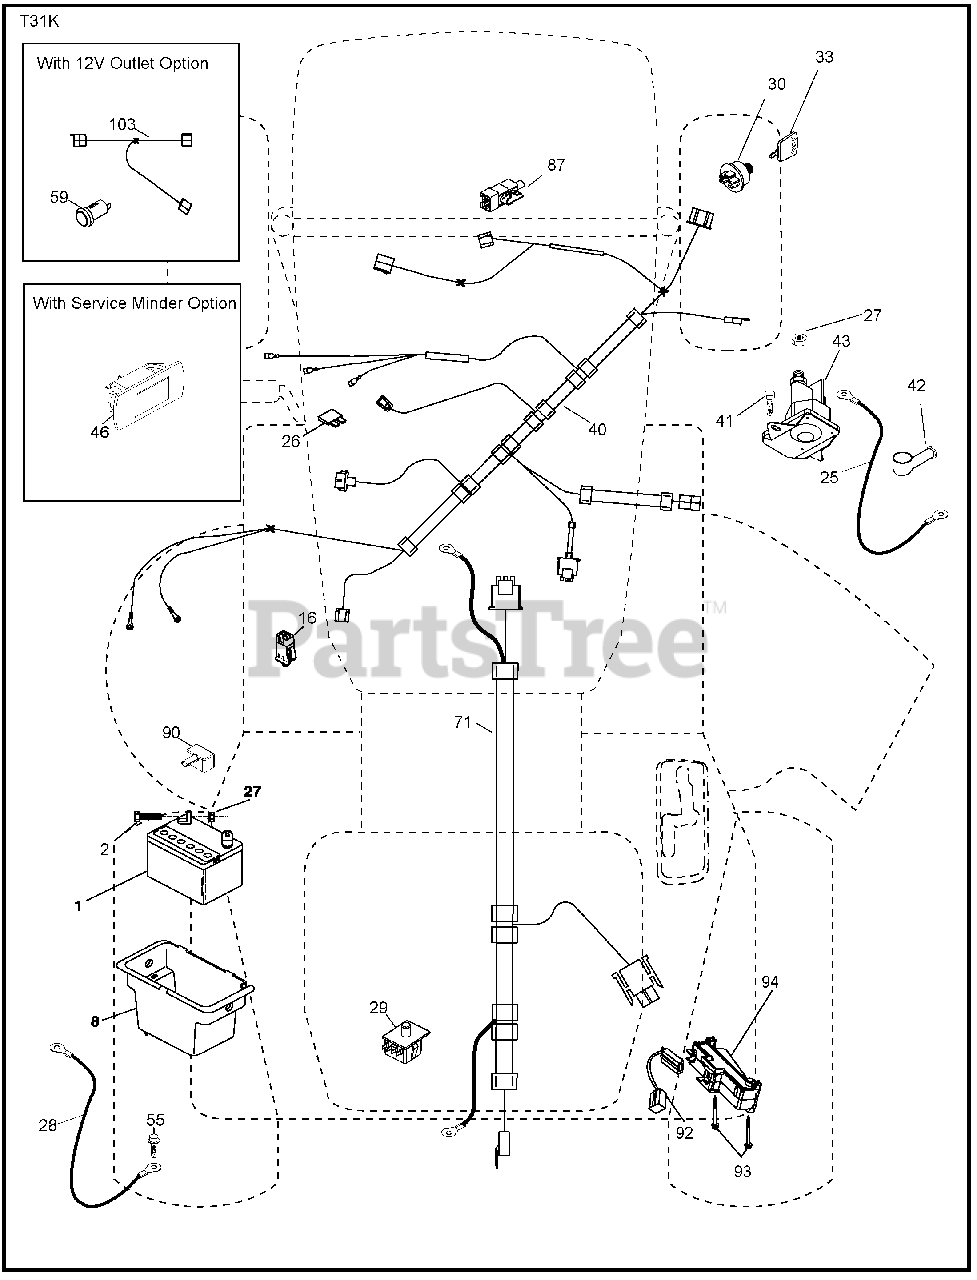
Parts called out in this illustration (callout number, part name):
2	Bolt Hex Hd 1/4-20 unc x 3/4
8	Box Battery
16	Switch Interlock
25	Cable Starter Battery 6 Ga. BL/Red 14.5
26	Fuse
27	Nut Keps Hex 1/4-20 unc
28	Cable Ground 18" Rear Battery Blk 6 Ga.
29	Switch Seat
30	Switch Ign
33	Key/Chain
40	Harness Ign
41	Screw 1/4-20 unc x 1/2
42	Cover Terminal Red
43	Solenoid
55	Screw 5/16-18 x 3/4
71	Harness Ign. Chass.
87	Switch Interlock Clutch
90	Cover Terminal
92	Harness Pigtail Reverse Switch
93	Screw Plastic 10-14 x 2.0
94	Modual Reverse ROS
